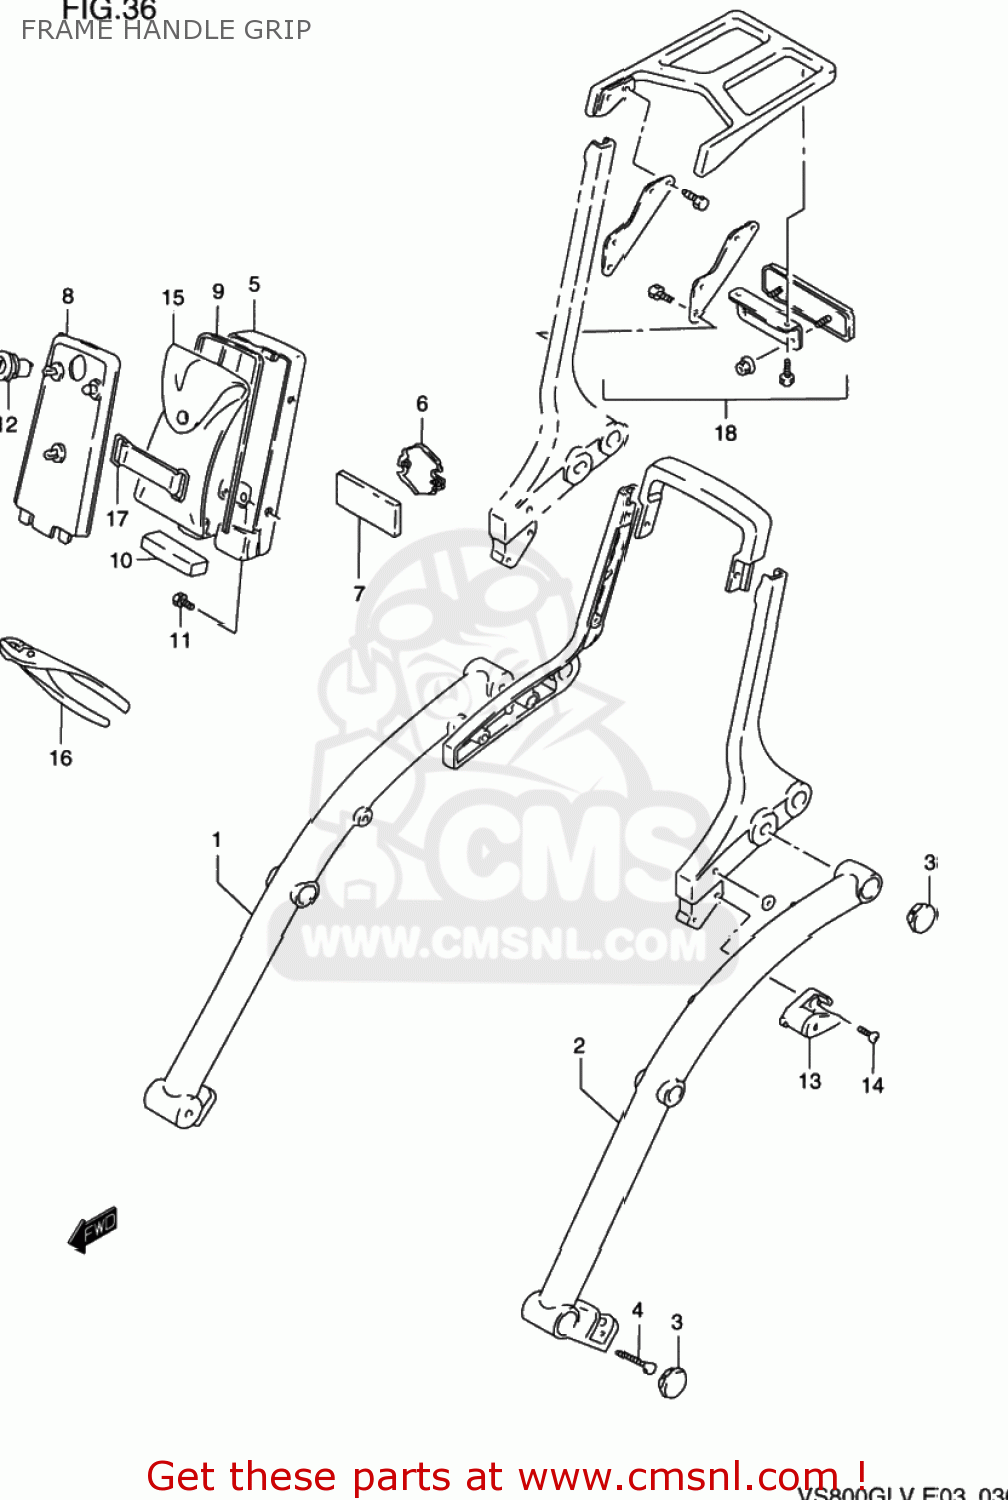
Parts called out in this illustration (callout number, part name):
1	GRIP,FRAME HANDLE,RIGHT
2	GRIP,FRAME HANDLE,LEFT
3	CAP,FRAME HANDLE GRIP
4	BOLT
5	HOLDER,TOOL
6	EMBLEM
7	TAPE,TOOL BAG PROTECTOR
8	HOLDER,TOOL FR
9	MOLDING,TOOL HOLDER RR
10	CUSHION,TOOL BACK
11	BOLT
12	LOCK SET,TOOL HOLDER
13	LOCK SET,HELMET
14	SCREW
15	TOOL ASSY
16	PLIER(150)
17	BAND
18	CARRIER SET,SPORT
